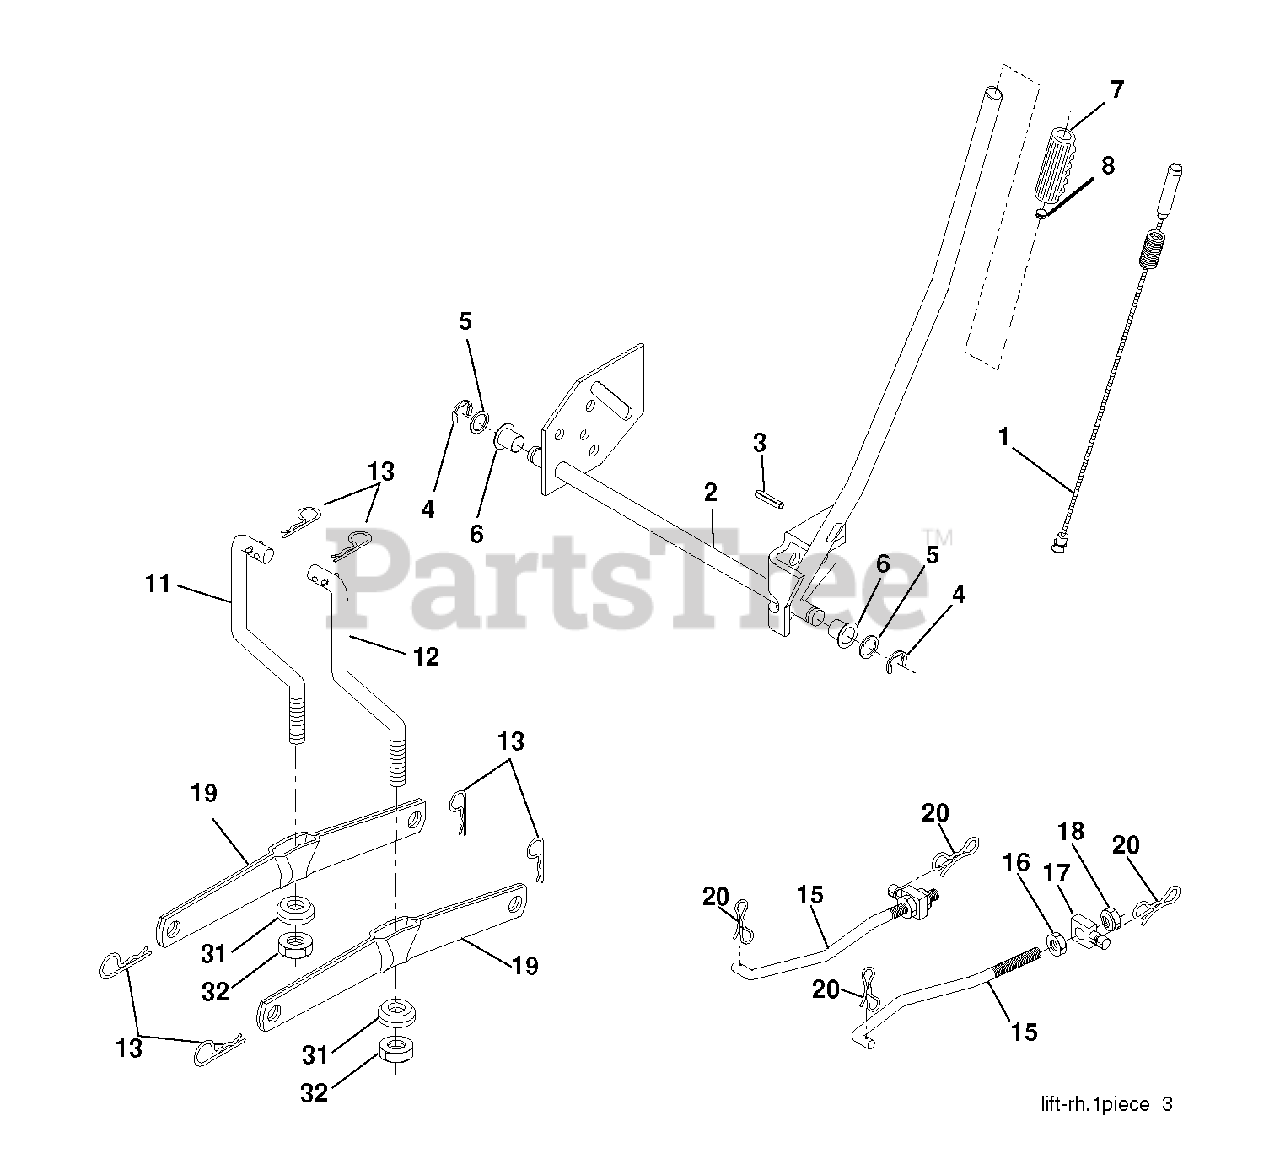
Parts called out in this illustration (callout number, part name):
1	PLUNGER.ASM.LIFT.LVR.BLK.17.32
2	SHAFT ASM R HANDLE
4	RETAINING RING LT
6	BEARING.NYLON
7	GRIP
8	PLUNGER BUT KIT
11	LINK LIFT LH
12	LINK LIFT RH
13	RETAINER-SPRNG RB
15	LINK.SUSPENSION.FRONT
16	NUT
18	NUT
19	ARM.REAR.SUSPENSION
20	PIN.COTTER.7/16.BOW TI
31	BEARING.PIVOT.LIFT
32	NUT CROWNLOCK 3/8-24
